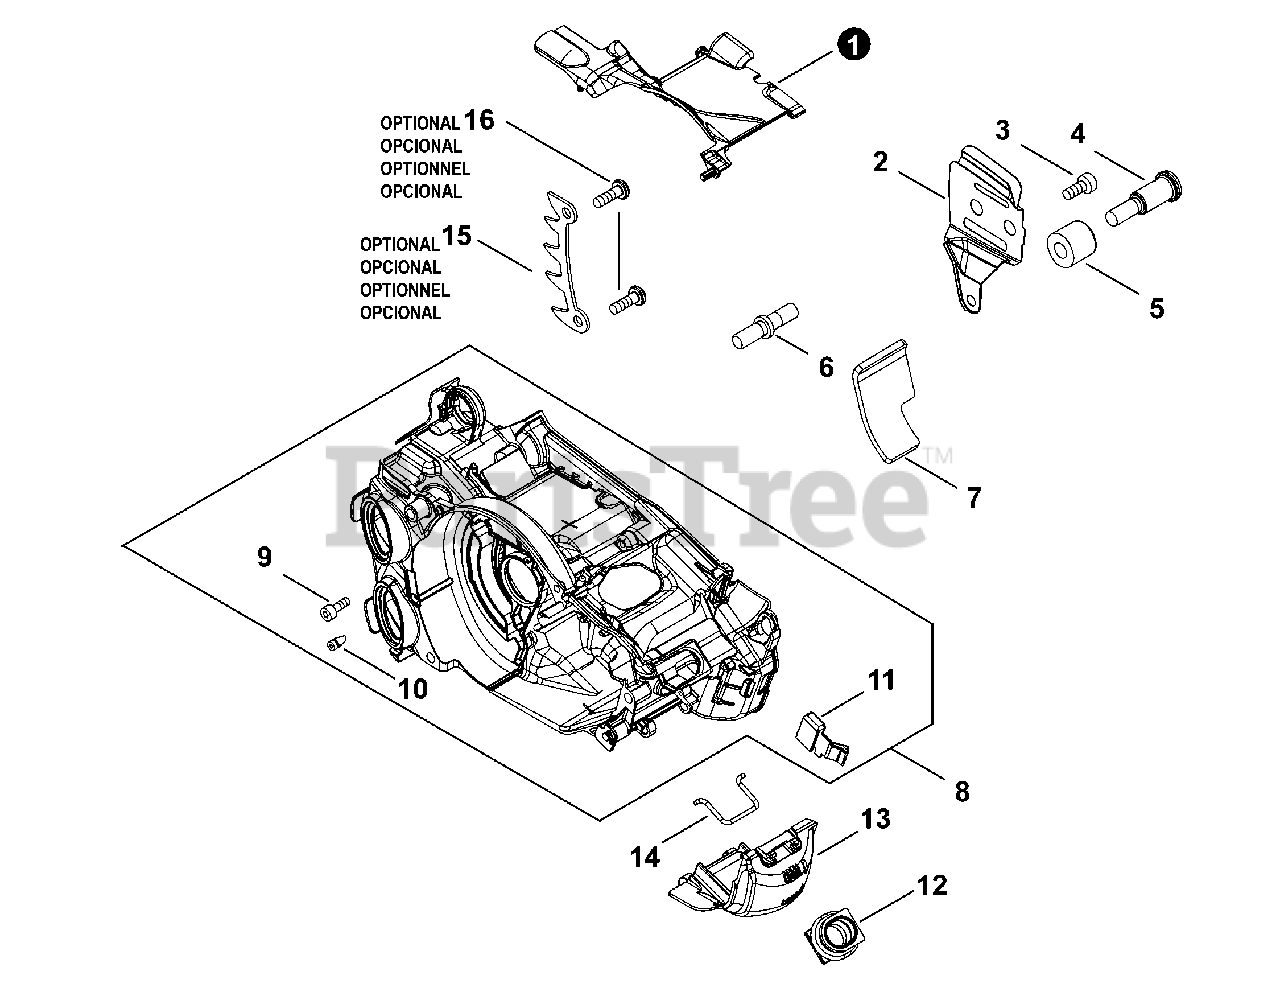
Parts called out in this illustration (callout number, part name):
1	COVER, DUST
2	PLATE, GUIDE - INNER
5	CATCHER, CHAIN
6	STUD, GUIDE BAR
7	SHIELD, HEAT
8	ENGINE COVER ASSY
9	BOLT, TORX 4×16
10	VENT ASSY
11	SHUTTER, AIR
12	PIPE, INTAKE
13	COVER, SPARK PLUG
14	RETAINER, COVER
15	SPIKE, BUMPER
16	BOLT, TORX 5×12
